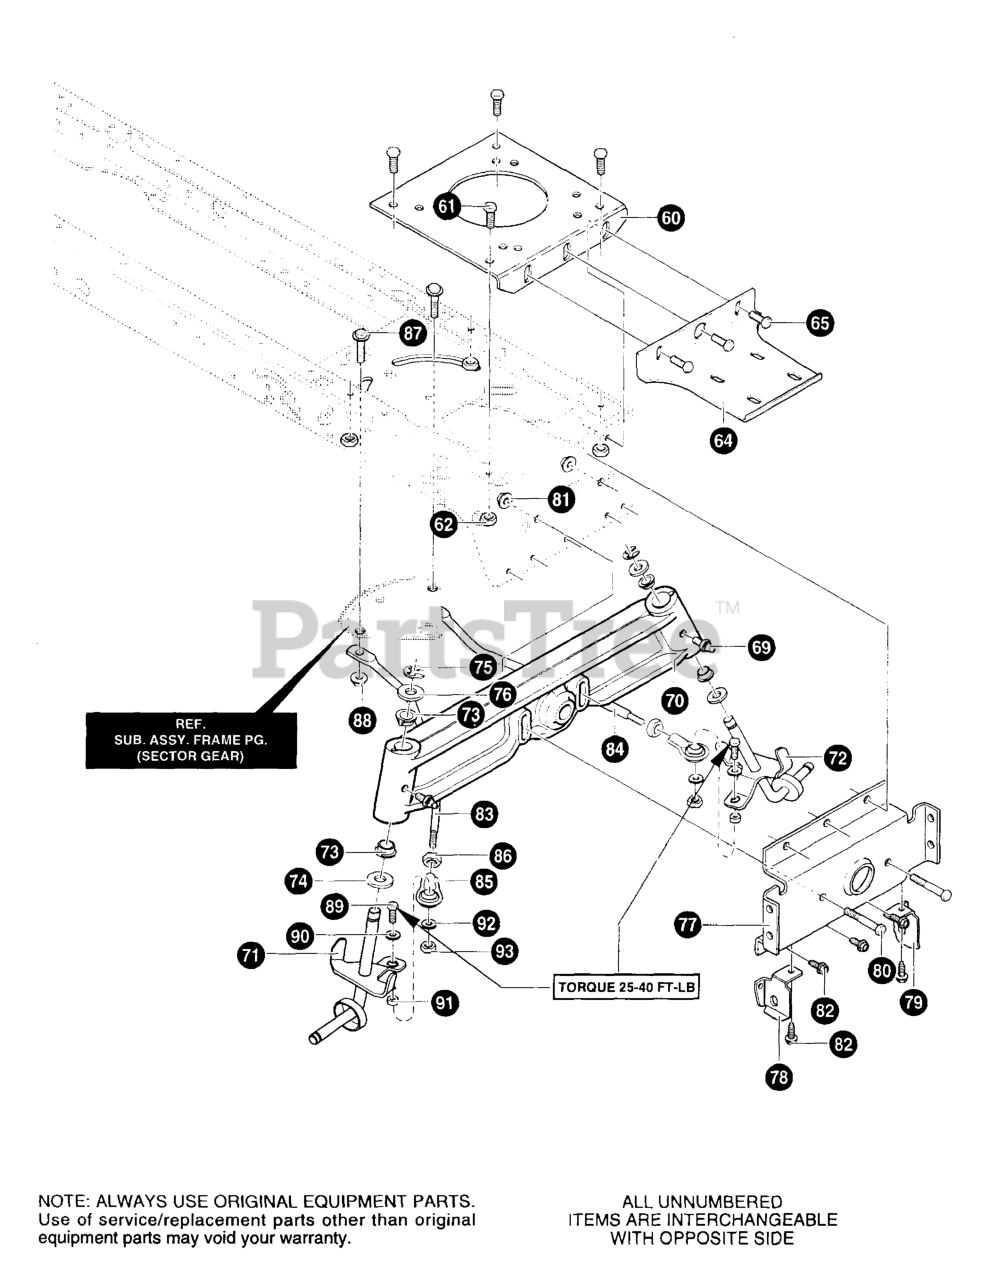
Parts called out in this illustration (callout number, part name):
60	PLATE, ENGINE
61	SCREW, 5/16-18 x 0.75 HHWATAP
62	NUT, 5/16-18 WDFLLK (15X88)
64	BRACKET, MUFFLER
65	SCREW, 5/16-18 x 0.75 HHWATAP
69	ZERK, GREASE FITTING
70	AXLE, FRONT CAST IRON
71	SPINDLE, RH/STD. SPIN/NO BRG.
72	SPINDLE, LH/STD. SPIN/NO BRG.
73	BEARING, SPINDLE
74	WASHER, FLAT .766 x 1.62 ID
75	E-RING .574 IDX.050/.750 SH 11 X3
76	WASHER, FLAT .765 x 1.81 x .059
77	HANGER, AXLE
78	HANGER DECK RH
79	HANGER DECK LH
80	SCREW 5/16-24X2.75
81	NUT, 5/16-24 NF-2 HEXFLLK
82	SCREW 5/16-18X.75HHWATAP
83	ROD, DRGLNK/RH/ADJUST-5/8"
84	ROD, DRGLNK/LH/ADJUST-5/8"
85	TIE ROD END, 1/2-20
86	NUT, 1/2-20 HXJAM
87	BOLT, HHSH (9X57)
88	NUT, 3/8-16 HWDFLLK MACK 15X84
89	BOLT, .500X1.18 HHSH 3/8-16
90	WASHER, FLAT .515X1.37X.119
91	SPACER, SLEEVE .515X.70X.
92	WASHER. FLAT /378X.75X.08
93	NUT, 3/8-16 REGHEXCTRLK
